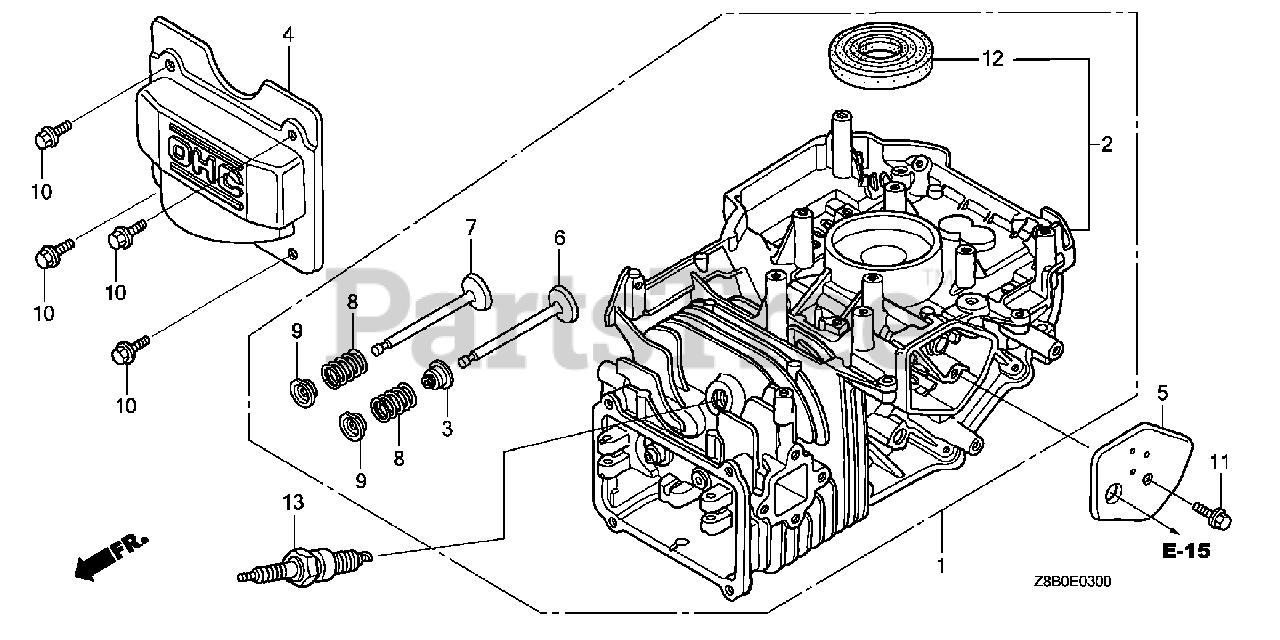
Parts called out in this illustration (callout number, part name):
1	CYLINDER ASSY.
3	SEAL, VALVE STEM
4	COVER, HEAD
5	COVER, BREATHER (BREATHER VALVE ASSY.)
6	VALVE, IN. (ROCKNEL)
6	VALVE, IN.
7	VALVE, EX.
8	SPRING, VALVE
9	RETAINER, VALVE SPRING
10	BOLT, FLANGE (6X12) (CT200)
11	BOLT, FLANGE (6X14) (CT200)
12	OIL SEAL (25.4X62X6)
13	SPARK PLUG (BPR6ES) (NGK)
